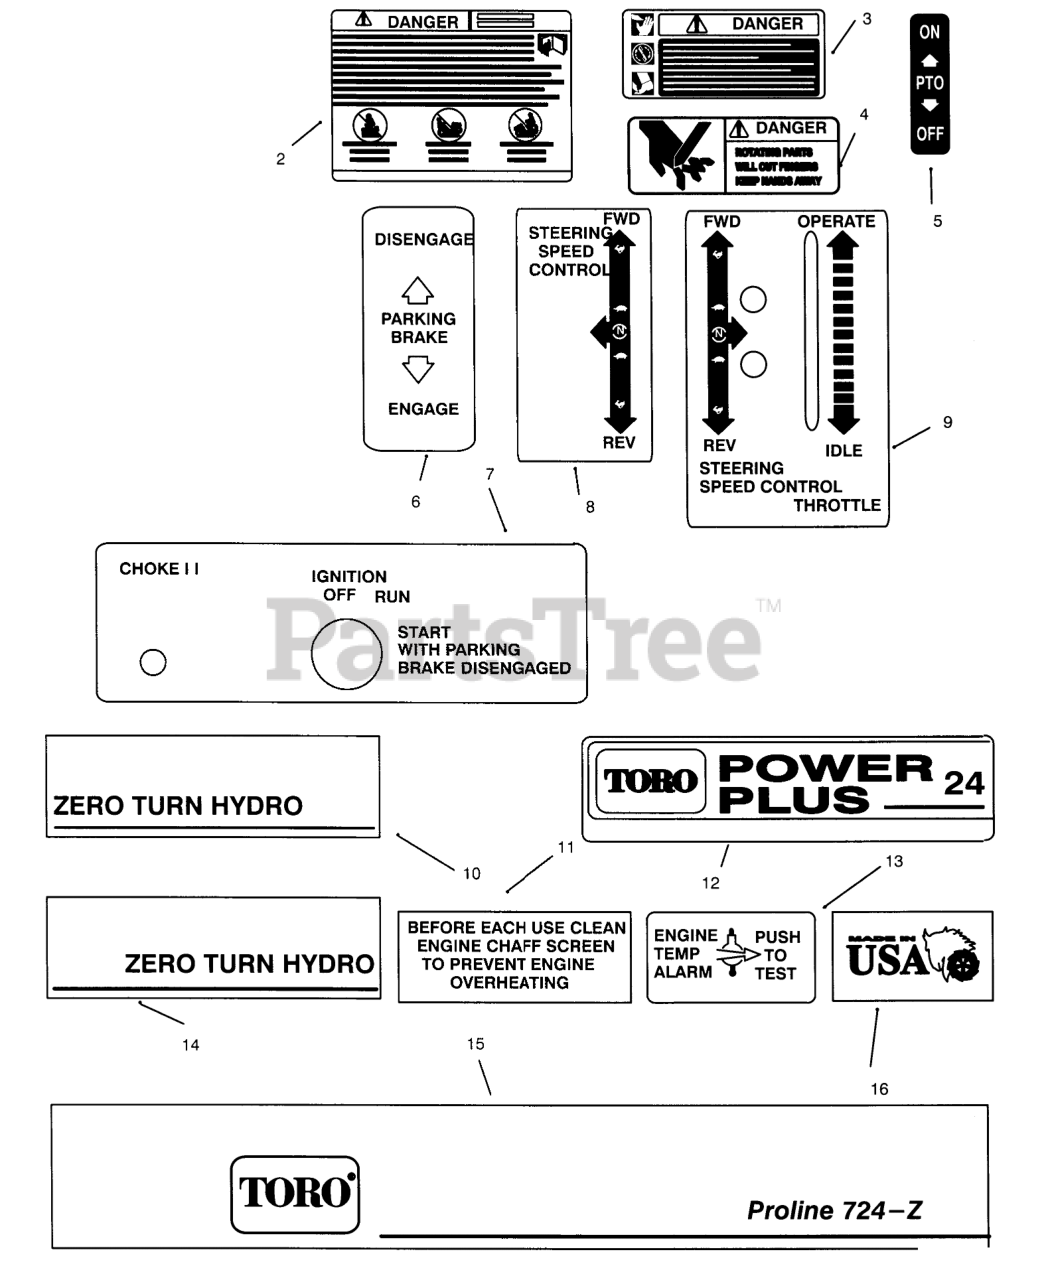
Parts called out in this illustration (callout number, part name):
2	DECAL-DANGER
3	DECAL-DANGER
4	DECAL - DANGER
5	DECAL-PTO
6	DECAL-PARKING BRAKE
7	DECAL-CHOKE/IGNITION
8	DECAL-STRG SPEED CNT
9	DECAL THROTTLE
10	DECAL-ZERO TURN R.H.
11	DECAL-ENGINE SCREEN
12	DECAL-PWR PLUS 24 PL
13	DECAL-TEMP ALARM
14	DECAL-ZERO TURN L.H.
15	DECAL-TORO 724-Z
16	DECAL - USA
